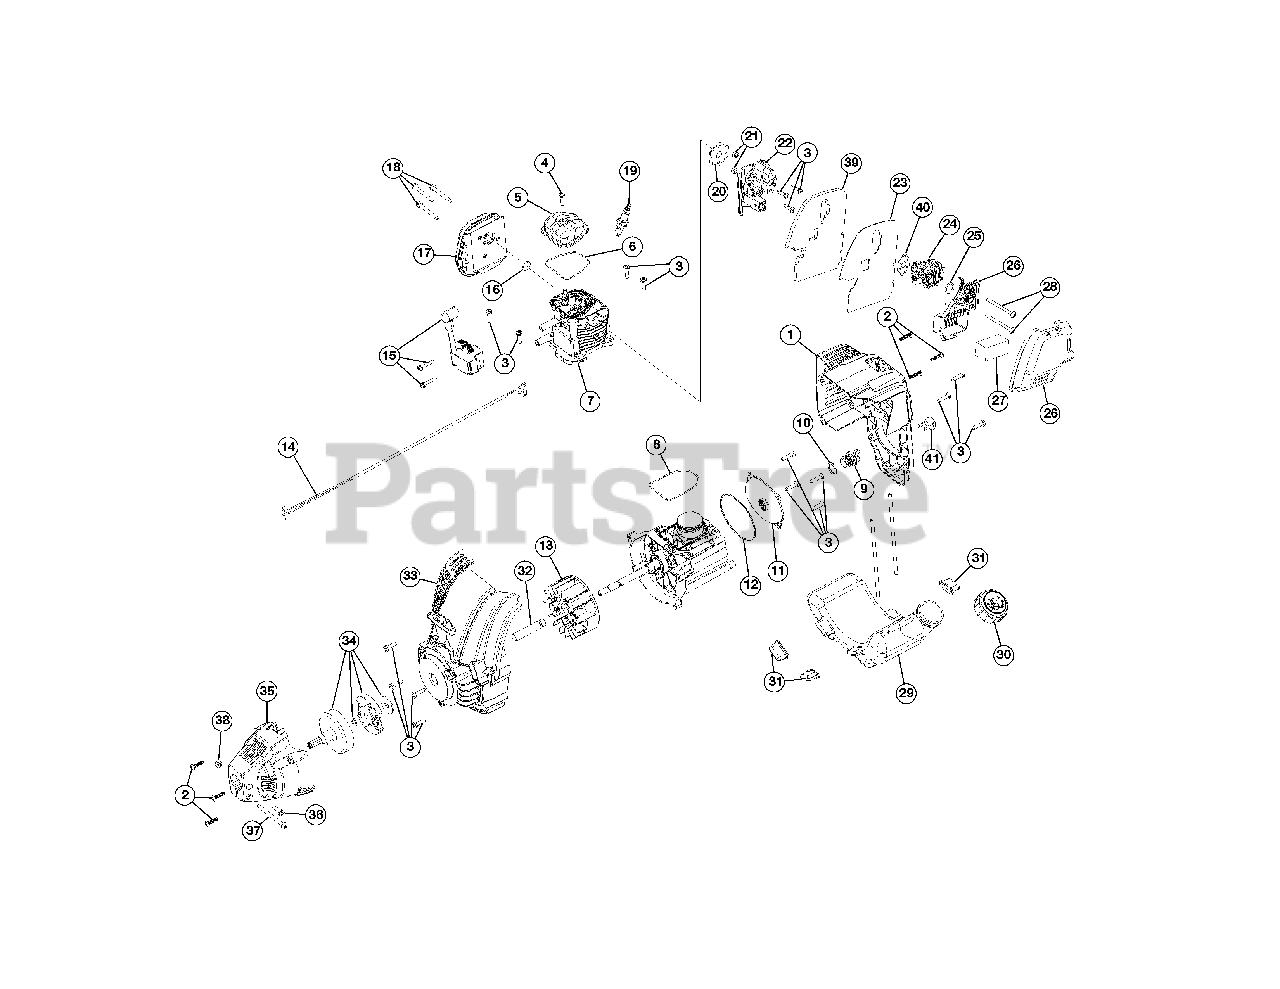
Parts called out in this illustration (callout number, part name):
1	Engine CoverAssembly (includes 2&3)
2	Cover Screw
3	HousingScrew
4	Rocker Cover Screw
5	Rocker Cover
6	Rocker Cover O-Ring
7	Cylinder Assembly (includes 3-6&8)
8	Cylinder O-Ring
9	Oil Plug (includes10)
10	Oil PlugO-Ring
11	Crankcase Cover
12	Crankcase Cover O-Ring
13	Flywheel Assembly
14	Lead Wires
15	Module Assembly
16	Muffler Gasket
17	Muffler Assembly (includes16&18)
18	Muffler Screw
19	Spark Plug
20	Insulator Gasket
23	Carburetor Gasket
24	Carburetor
26	Air Cleaner Cover Assembly (includes 27)
27	Air Filter
29	Fuel Tank Assembly w/FuelLines (includes 30)
31	Fuel Tank Pads
33	Starter Housing Assembly (includes 3)
34	Clutch Assembly
35	Clutch Cover (includes 2)
36	Anti-Rotation Screw
37	ClampScrew
39	Heatshield Carb.
41	Electric Start Plug
